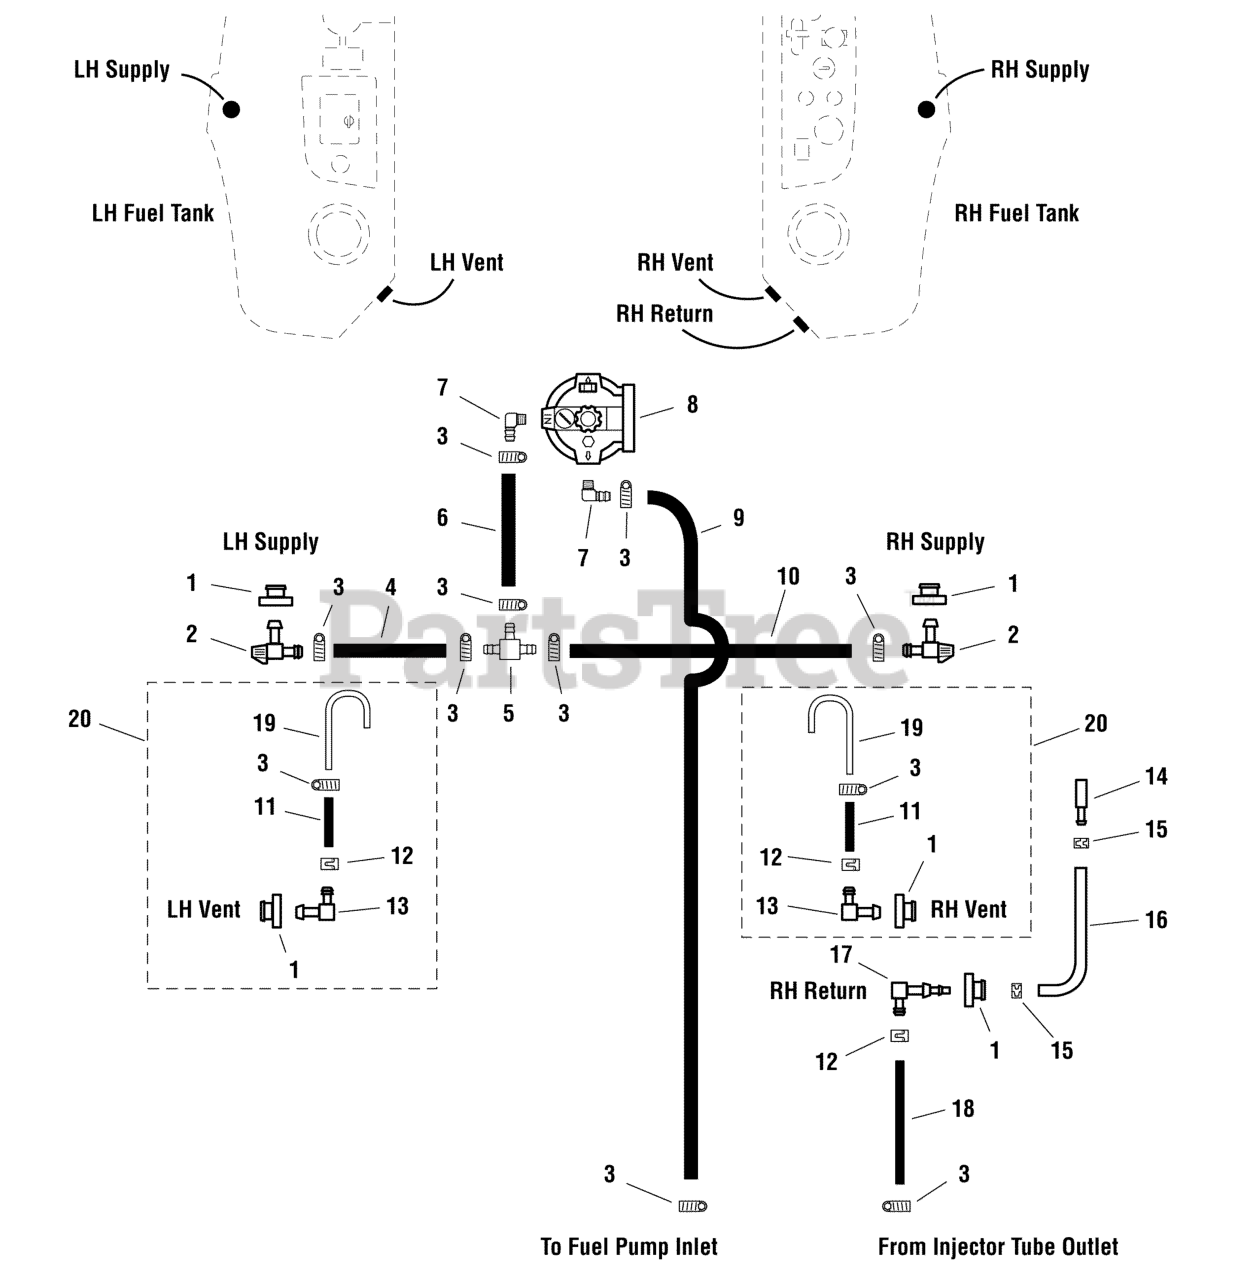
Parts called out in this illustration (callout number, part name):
1	BUSHING-FUEL TANK RED RUBBER
2	VALVE, FUEL SHUT OFF
3	CLAMP, #4 HOSE
4	HOSE, 3/8" FUEL, 34.00
5	FITTING, TEE, 1/2" HOSE
6	HOSE, 3/8" FUEL, 21.00"
7	1/4 NPT - 3/8 BEADED HOSE BARB
8	FILTER/WATER SEPERATOR ASS'Y.
8	FUEL FILTER
8	O-RING SEAL
9	HOSE, 3/8" FUEL, 59.00"
10	HOSE, 3/8" FUEL, 40.00"
11	HOSE, 1/4" FUEL, 27.00"
12	CLAMP, HOSE, EXTERNAL, 1/2 - RED
16	HOSE ASSEMBLY
18	HOSE, 1/4" FUEL, 30.00"
19	VENT TUBE, DIESEL
20	KIT, FUEL TANK VENT LINE
